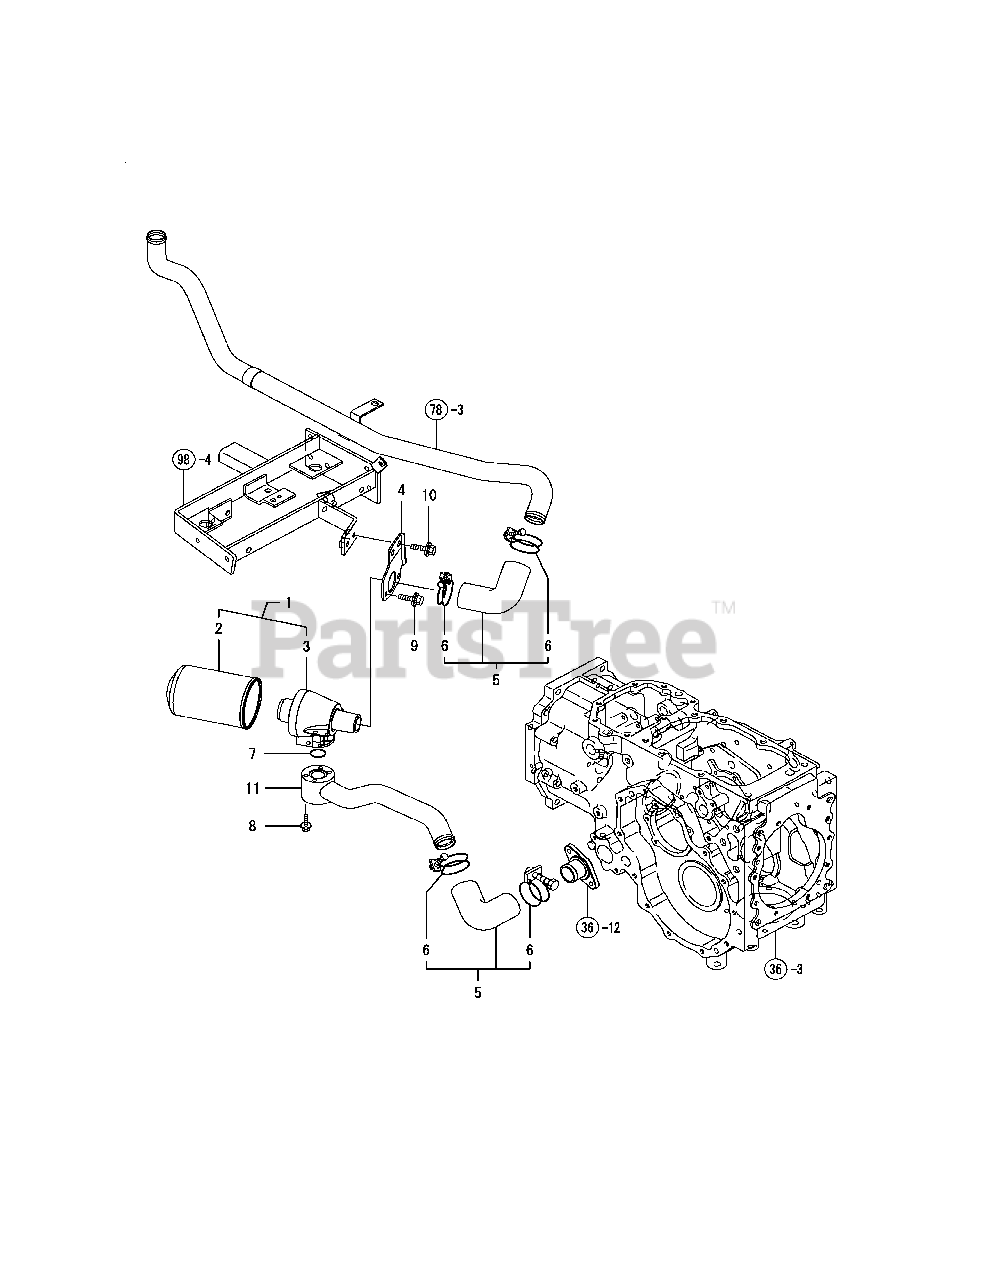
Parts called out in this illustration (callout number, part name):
1	OIL FILTER ASSY
3	FILTER ASSY, BLOCK
4	BRACKET, FILTER
5	HOSE ASSY, SUCTION
7	O-RING 1A G-25.0
8	BOLT M 6X 60 PLATED
9	BOLT M 8X 16 PLATED
10	BOLT M 8X 20 PLATED
11	PIPE, FILTER
